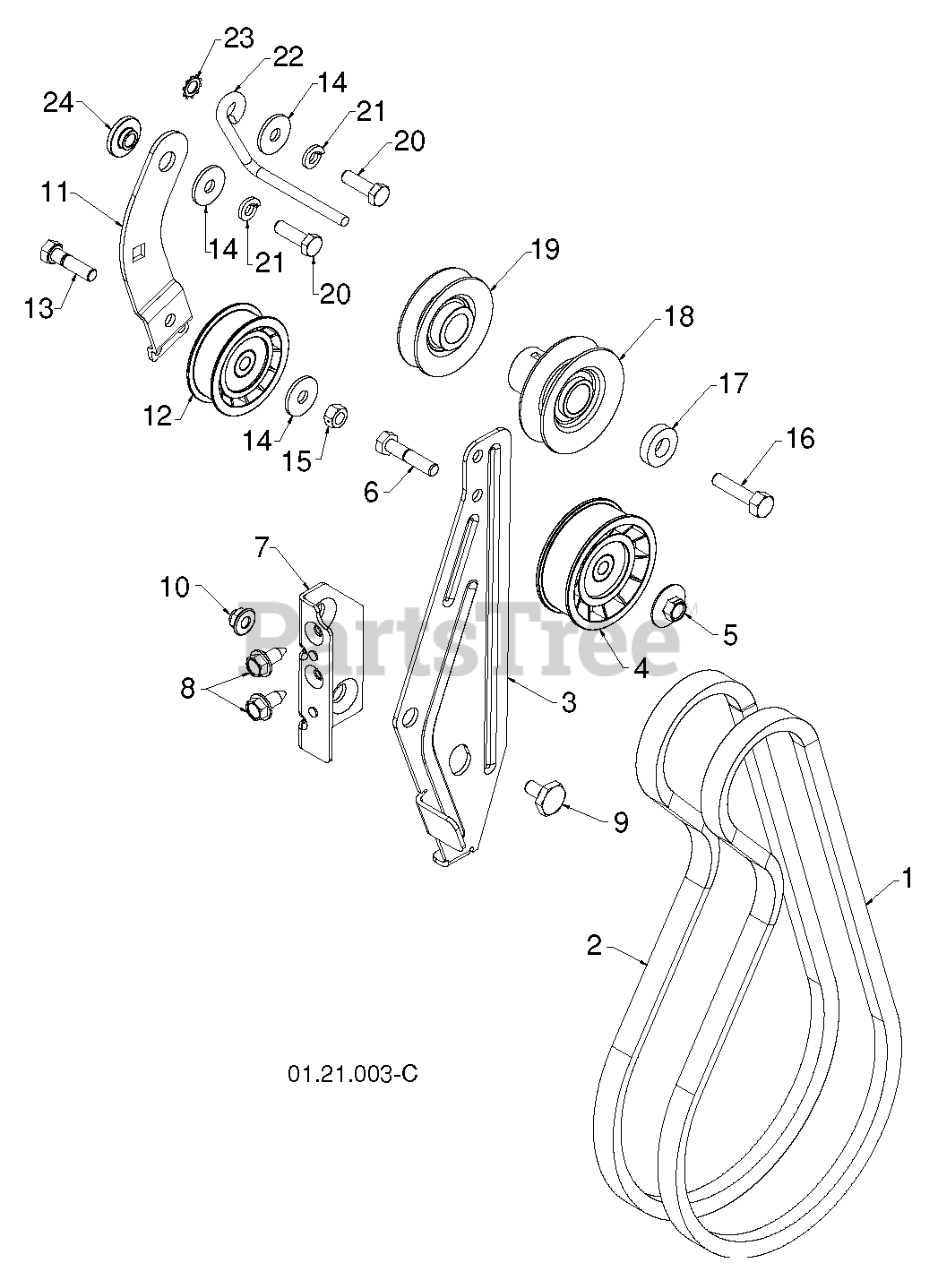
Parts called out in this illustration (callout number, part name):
1	BELT.V.IMPELLER
2	V-BELT TRACTION 34.25
3	ARM.IDLER.BRAKE.
4	PULLEY.W/SPACER.2.75
5	NUT.FLANGE.HEX.5/16X18.BLACK
6	HEX BOLT
7	RP BRACKET.IDLER.PIVOT
8	BOLT.5/16HEX.WHS.HD
9	BOLT.SHOULDER.1/2X12
10	NUT.LOCK.5/16-18
11	ARM, IDLER
12	PULLEY.W/SPACER.2.25
13	BOLT.5/16-18X1-1/4 FULL.THREAD
14	STEEL WASHER
15	NUT.71038.31-18.HEX.NYLOCK
16	SCREW, HEX HD 3/8-24 X 1-3/8
17	WASHER, FLAT 3/8
18	PULLEY.IMPELER.
19	PULLEY.ENG.TRACTION
21	WASHER.LOCK.HVY.HLCL.SPR.5/16
22	BELT.GUIDE.RH
23	WASHER EXT TOOTH LOCK 5/16
24	RP BUSHING, IDLER PIVOT
